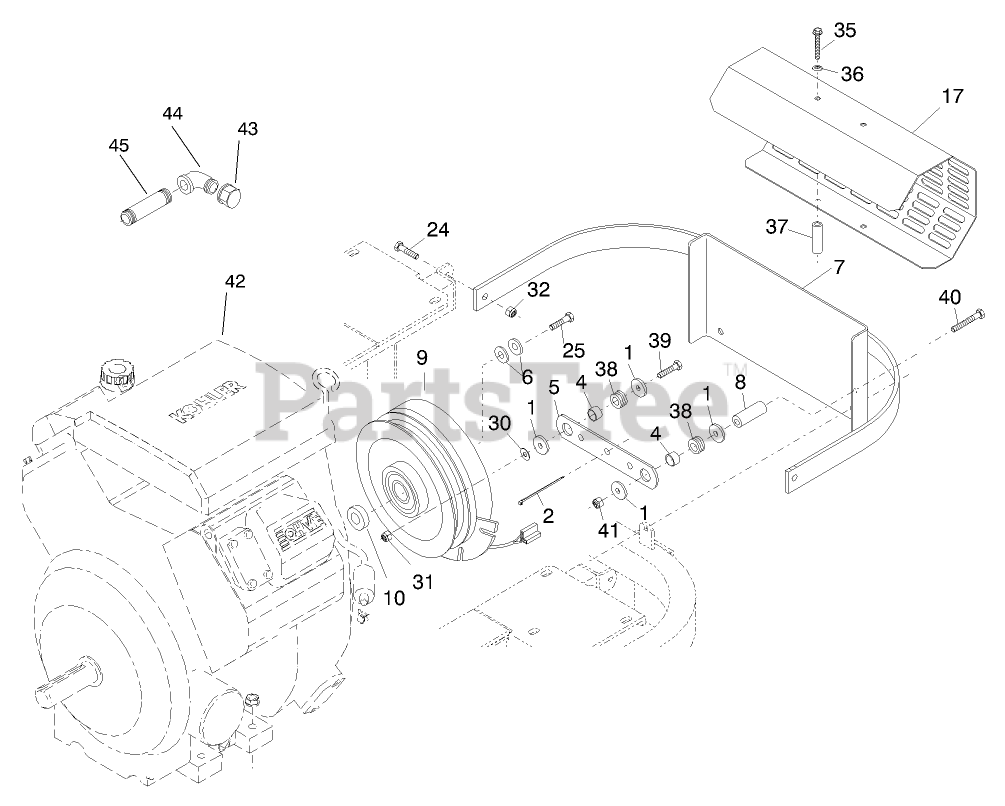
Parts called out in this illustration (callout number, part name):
1	Washer
2	Tie-Plastic
4	Spacer
5	Strap
6	Disc-Spring
7	Guard-Engine
8	Spacer
9	Clutch
10	Spacer
17	Guard-Muffler
24	SCREW-HH
25	SCREW-HH
30	WASHER-FLAT
31	NUT-HF
32	NUT-FLANGE
35	Screw-HH
36	Washer-Lock
37	Spacer
38	Grommet
39	SCREW-HH
40	Screw-HH
41	Nut-Lock
42	Kohler Command
43	Cap
44	Elbow Street
45	Nipple
